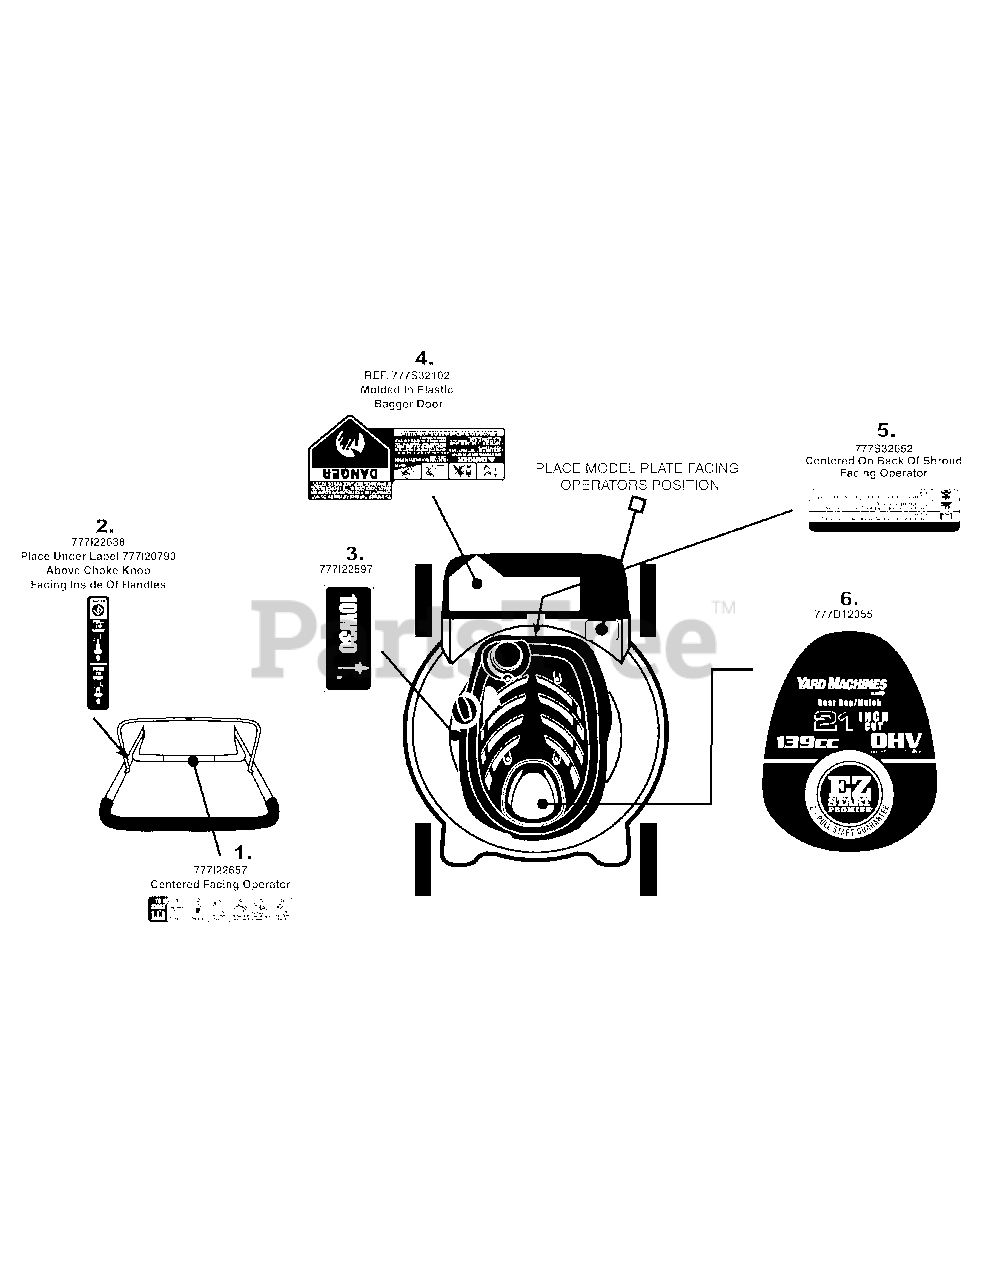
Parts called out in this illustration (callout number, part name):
1	LABEL-MOWER HANDLE
2	LABEL-MOWER HANDLE:CHOKE START/RUN
3	LABEL:MOWER SHROUD
4	LABEL
5	LABEL:MOWER:ENGINE SHROUD
6	LABEL-MOWER SHROUD YM REAR BAG 21"
